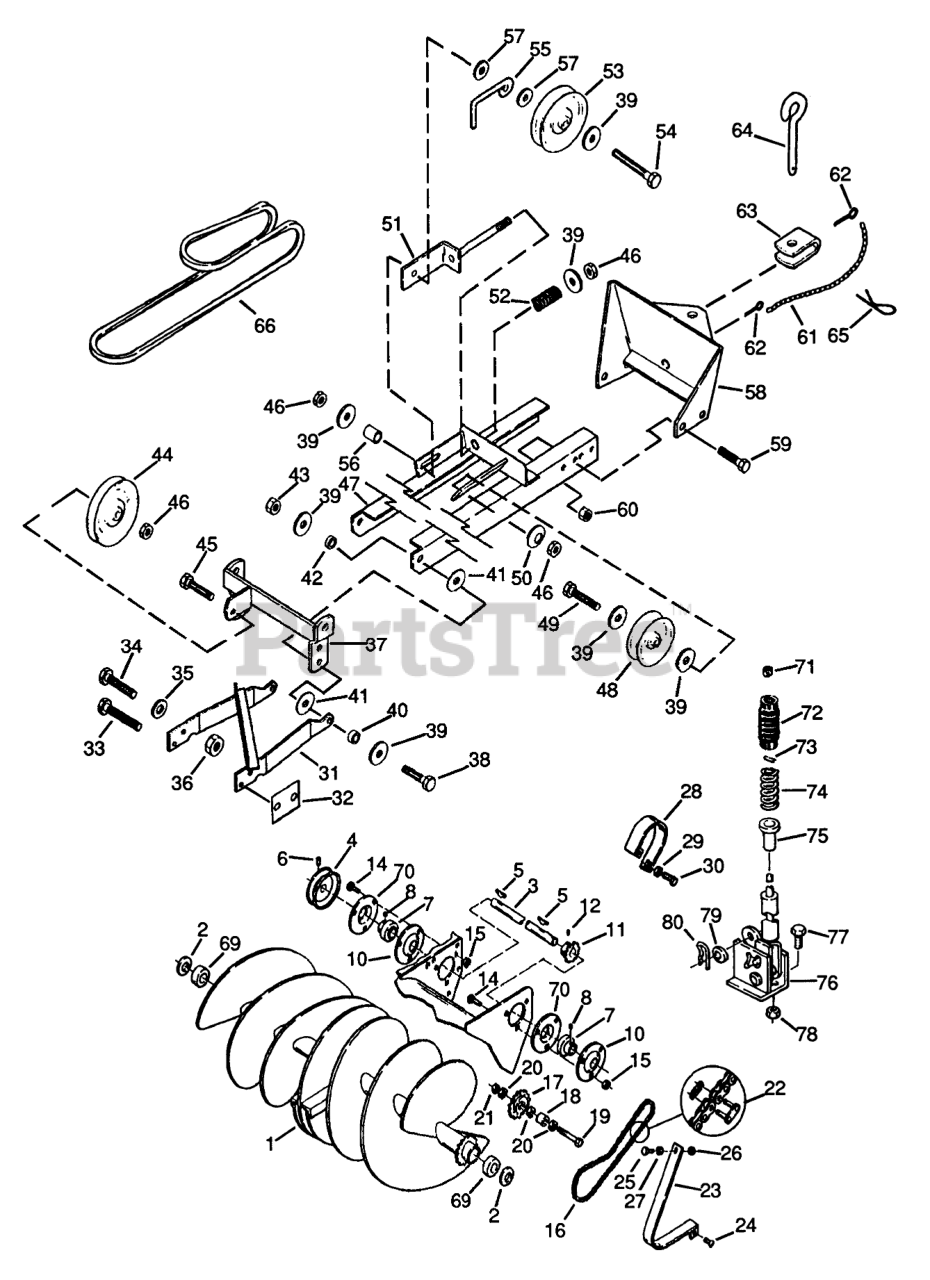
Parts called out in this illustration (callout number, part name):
3	SHAFT
4	PULLEY
7	BEARING AND COLLAR
10	FLANGE-ZERK RELUBE
16	CHAIN-64 PITCHES
18	SPACER
28	GUARD-CHAIN *R
30	Bolt
37	ASS'Y-FRONT LINK *R
39	WASHER
40	SPACER
47	ASS'Y-SUB FRAME *R
52	SPRING-COMPRESSION
56	SPACER
63	YOKE *R
64	PIN-TOOL
65	Hairpin Cotter
66	BELT-V 127.0 E L
69	BEARING-BALL
70	FLANGE
71	CAP-ROD, PLUNGER
72	HANDGRIP
73	PIN-SPIROL
74	SPRING-COMPRESSION
75	RETAINER-SPRING
76	ASS'Y-LIFT HANDLE *R
80	Hairpin
